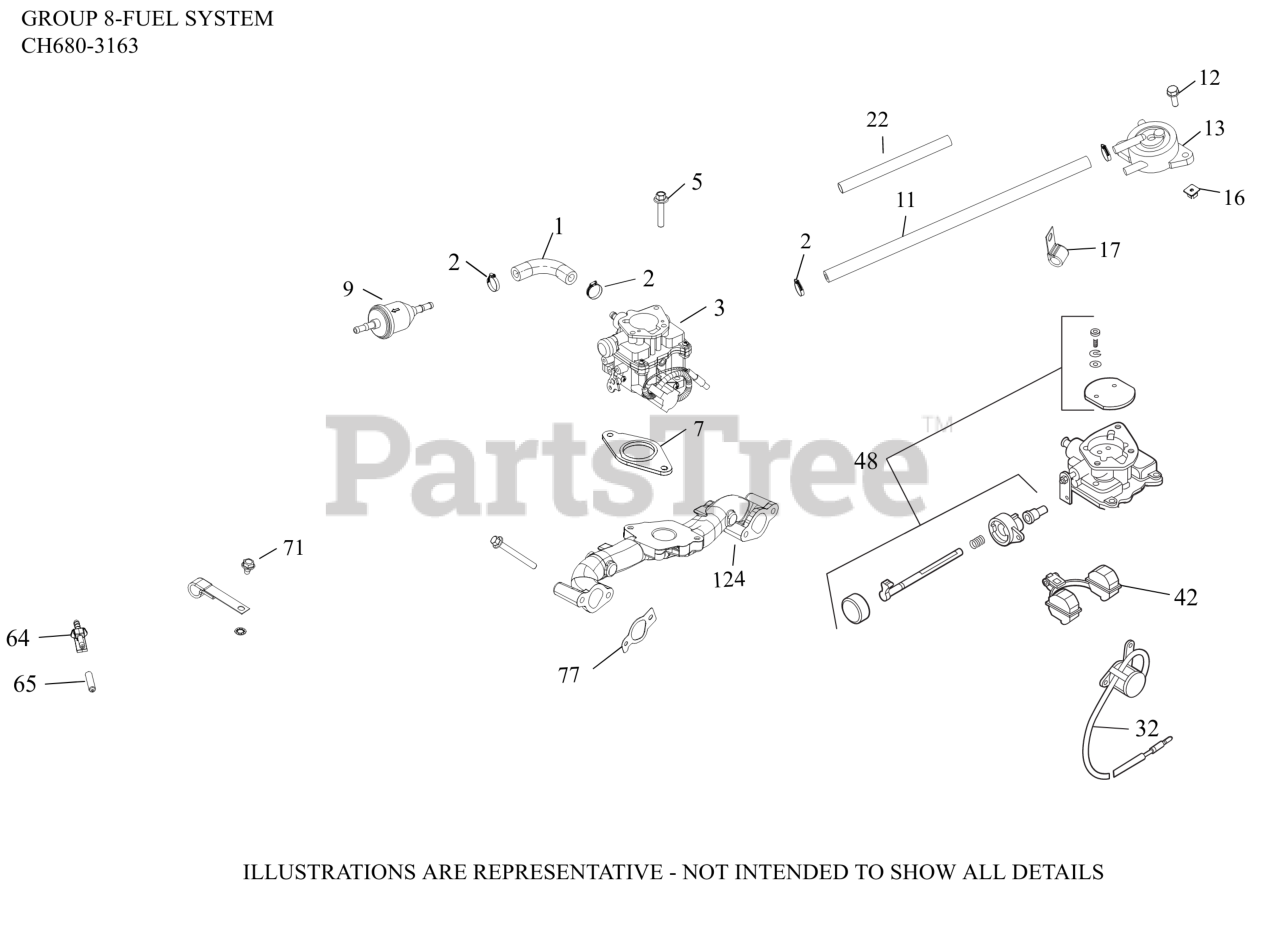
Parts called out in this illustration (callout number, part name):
1	HOSE,LW PERM.FUEL 24.00"-USE 25 111 81-S
2	CLAMP, HOSE (KM)-USE 25 237 31-S
3	KIT, CARBURETOR COMPLETE
5	SCREW, FLG M6X1.0X30
7	GASKET, CARBURETOR
9	FILTER, FUEL
11	LINE, FLEXIBLE FUEL 15 1/2"
12	SCREW, TAP M6X1.7X18
13	PUMP, FUEL
16	NUT, PLASTIC - BLACK
17	CLIP, CABLE (KM)
22	SLEEVE,INSULATING 6.0 "-USE 24 431 02-S
32	KIT, SOLENOID
42	KIT, REPAIR FLOAT
48	KIT, REPAIR CHOKE
64	CONNECTOR, EVAPORATIVE
65	CAP, MASKING
71	SCREW, THREAD FORMING
77	KIT, INTAKE MANIFOLD GASKET
124	MANIFOLD, METAL INTAKE
NI	KIT, HIGH ALT (4000-8000 FT)
NI	KIT, HIGH ALT (8,000+ FT)
NI	KIT, REPAIR CARBURETOR
